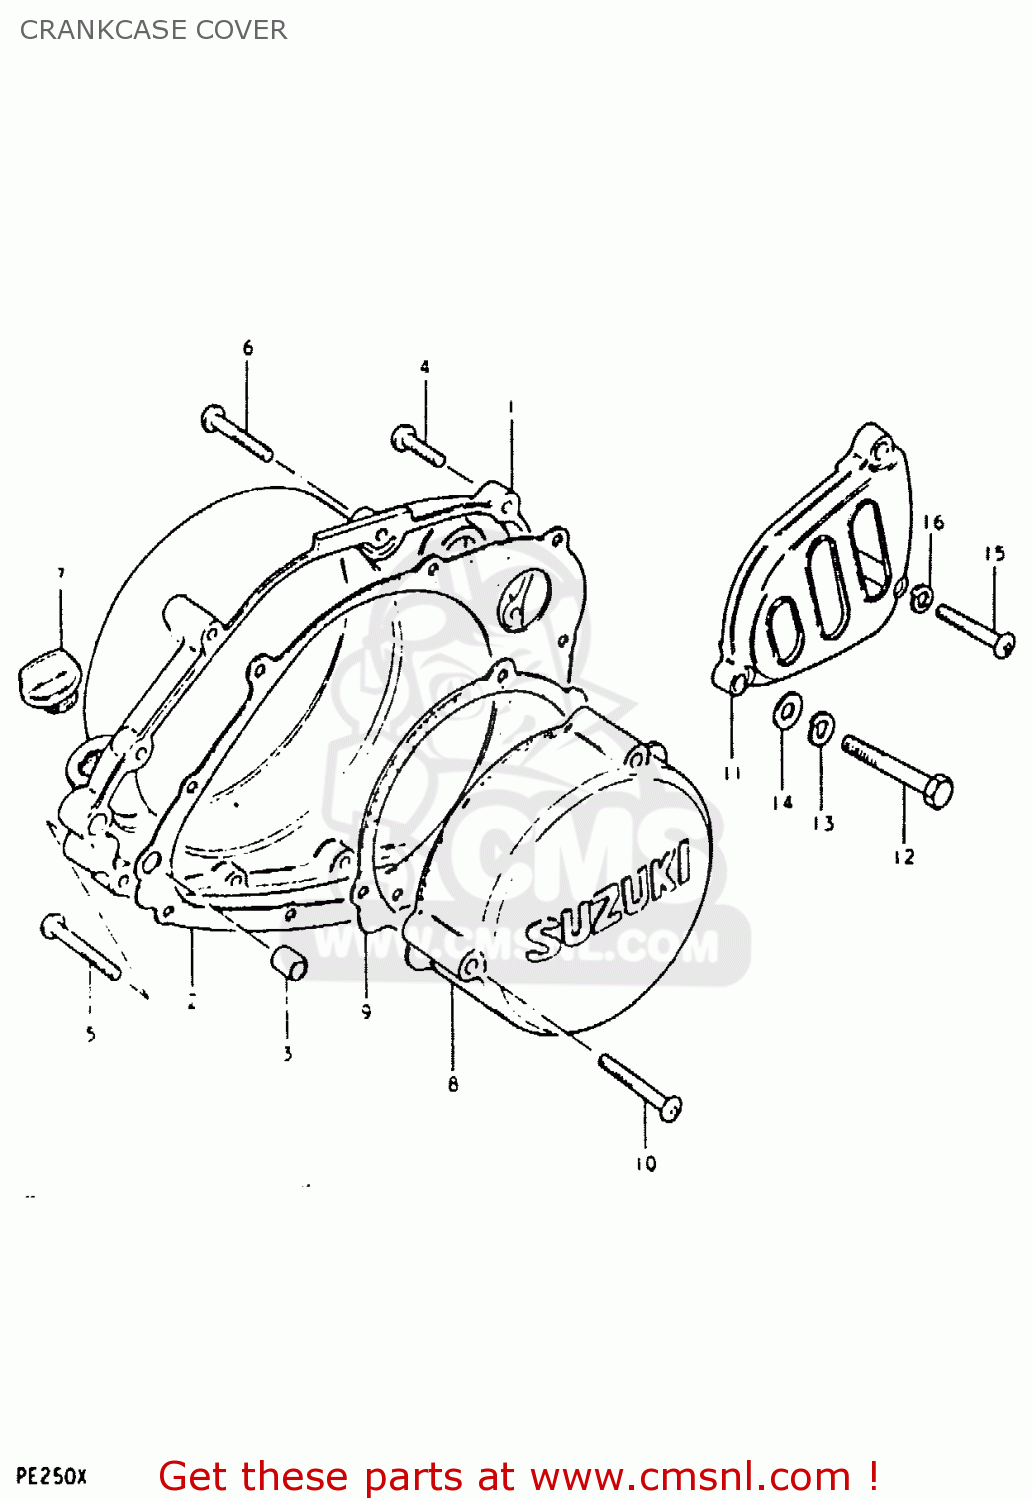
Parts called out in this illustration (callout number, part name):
1	COVER,CLUTCH
2	GASKET,CLUTCH COVER (MCA)
3	PIN
4	SCREW
5	SCREW (6X45)
6	SCREW 6X30
7	PLUG,OIL FILTER
8	COVER,MAGNETO
9	GASKET,MAGNETO COVER (NAS)
10	SCREW
11	COVER,ENGINE SPROCKET
12	BOLT 8X55
13	LOCK WASHER
14	WASHER
15	SCREW
16	LOCK WASHER
